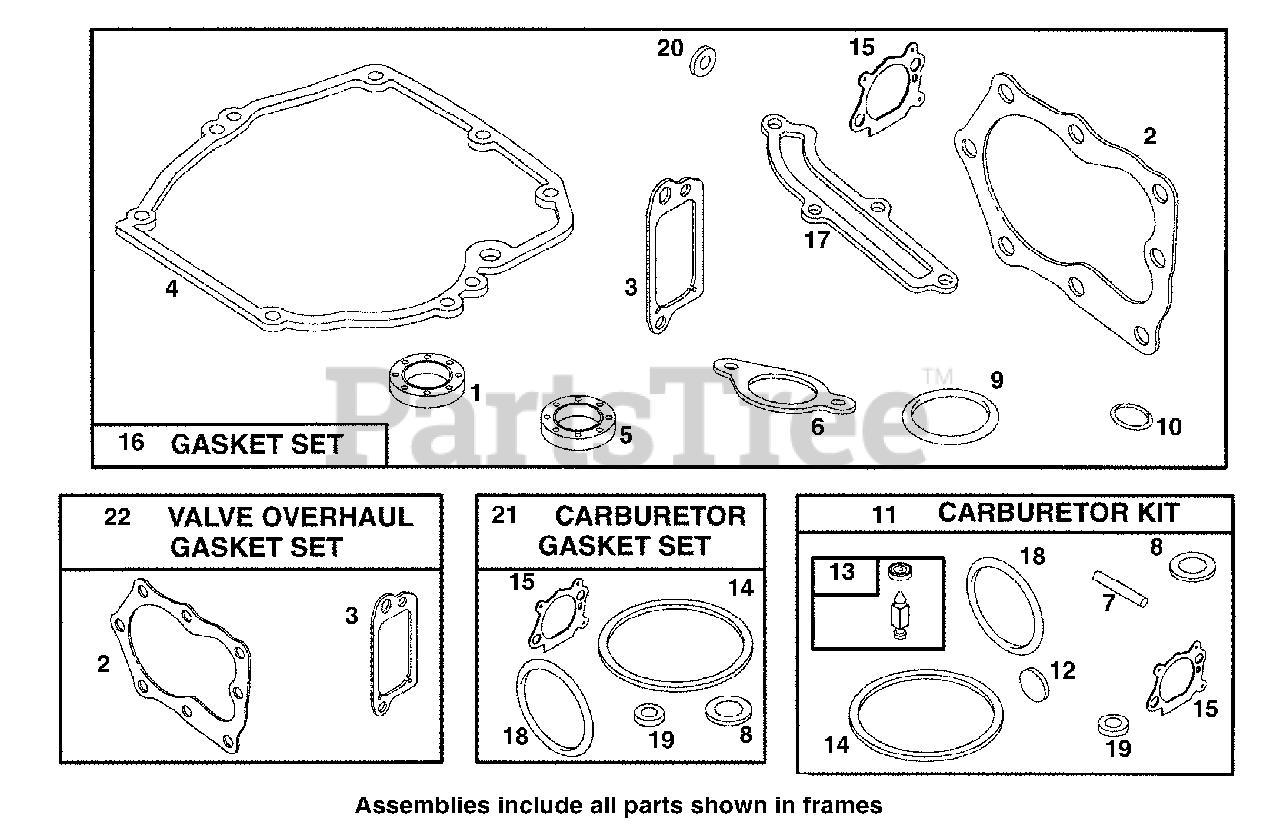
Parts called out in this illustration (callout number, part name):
1	Oil Seal
2	Cylinder Head Gasket
3	Breather Gasket
4	Crankcase Gasket
5	Oil Seal
6	Intake Gasket
7	Float Hinge Pin
8	Bowl Washer (Sold only in kit)
9	O-Ring Seal
10	O-Ring Seal
11	Carburetor Kit
12	Welch Plug (Sold only in kit)
13	Needle/Seat Kit
14	Bowl Gasket (Sold only in kit)
15	Air Cleaner Gasket
16	Gasket Set
17	Breather Passage Gasket
18	Intake Manifold Seal
20	Spacer
21	Carburetor Gasket Set
22	Valve Overhaul Gasket
